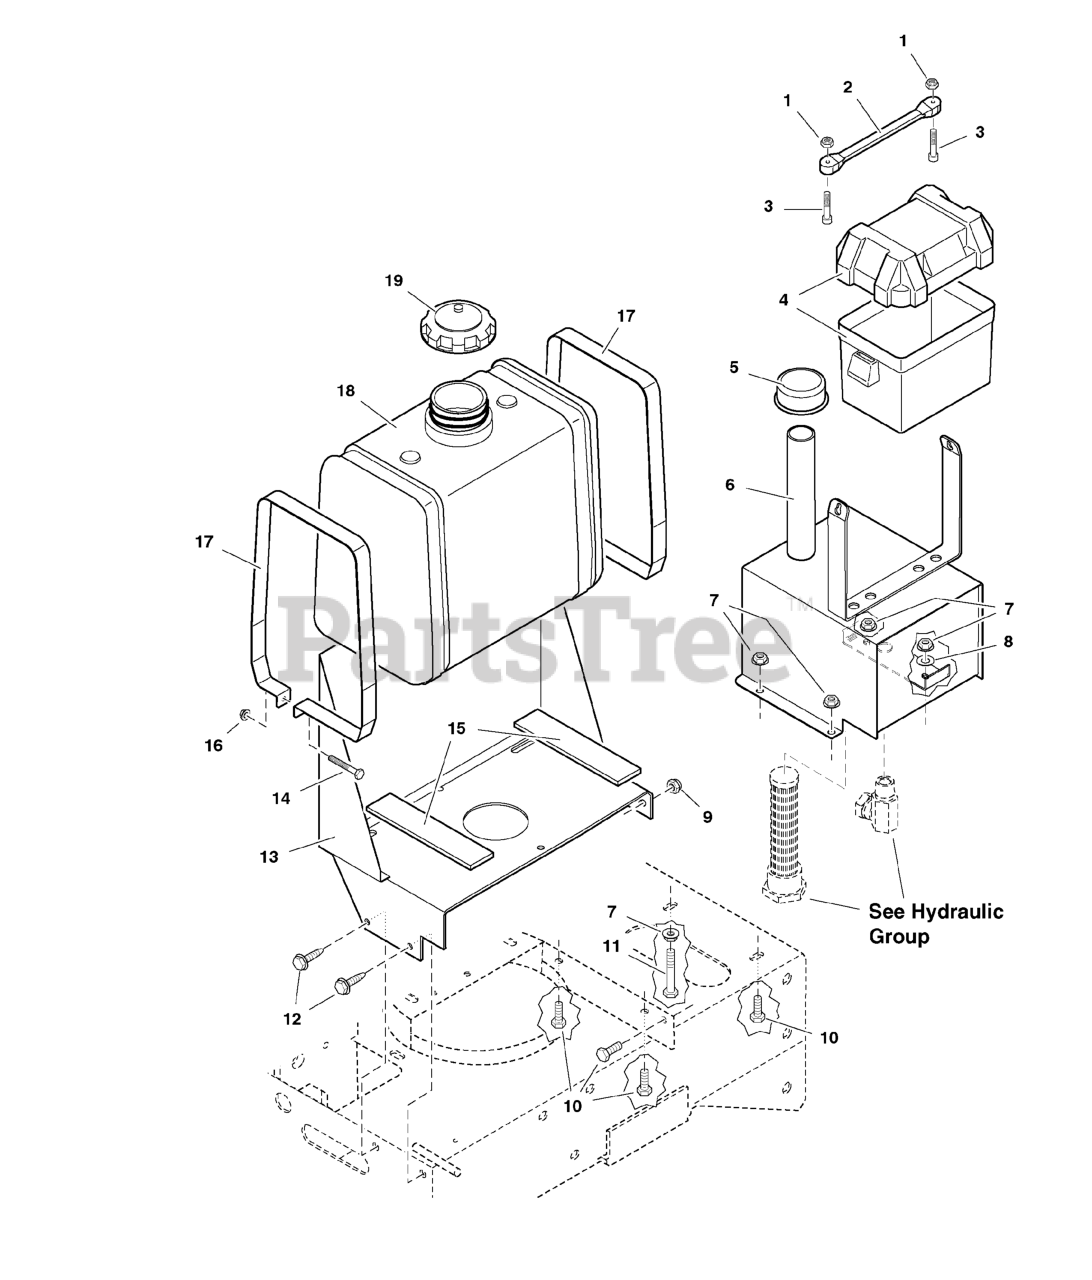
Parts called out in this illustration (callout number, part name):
1	NUT, #10-24 Hex Nylon Lock
2	RUBBER STRAP
3	SCREW, #10-24 X 1 RS, CZ
4	BATTERY BOX
5	BREATHER
6	HYDRO TANK ASSEMBLY, Complete
6	HYDRO TANK WELDMENT
6	FOIL TAPE
7	NUT, 5/16-18 HEX SERRATED FLANGE (SMALL)
8	WASHER, 5/16" SAE
9	NUT, 5/16-18 Hex Nylon Lock
10	BOLT, 5/16-18 X 3/4 GD5
11	BOLT, 5/16-18 x 1-3/4
12	BOLT, Self Tapping, 5/16-18 x 3/4
13	FUEL TANK MOUNT
14	BOLT, 1/4-20 X 1-1/2
15	RUBBER PAD
16	NUT, 1/4-20 HEX SERR. FLANGE
17	FUEL TANK STRAP
18	TANK, FUEL, PLASTIC, 6 GALLON W/ FUEL LINE
19	CAP, GASOLINE, VENTED
